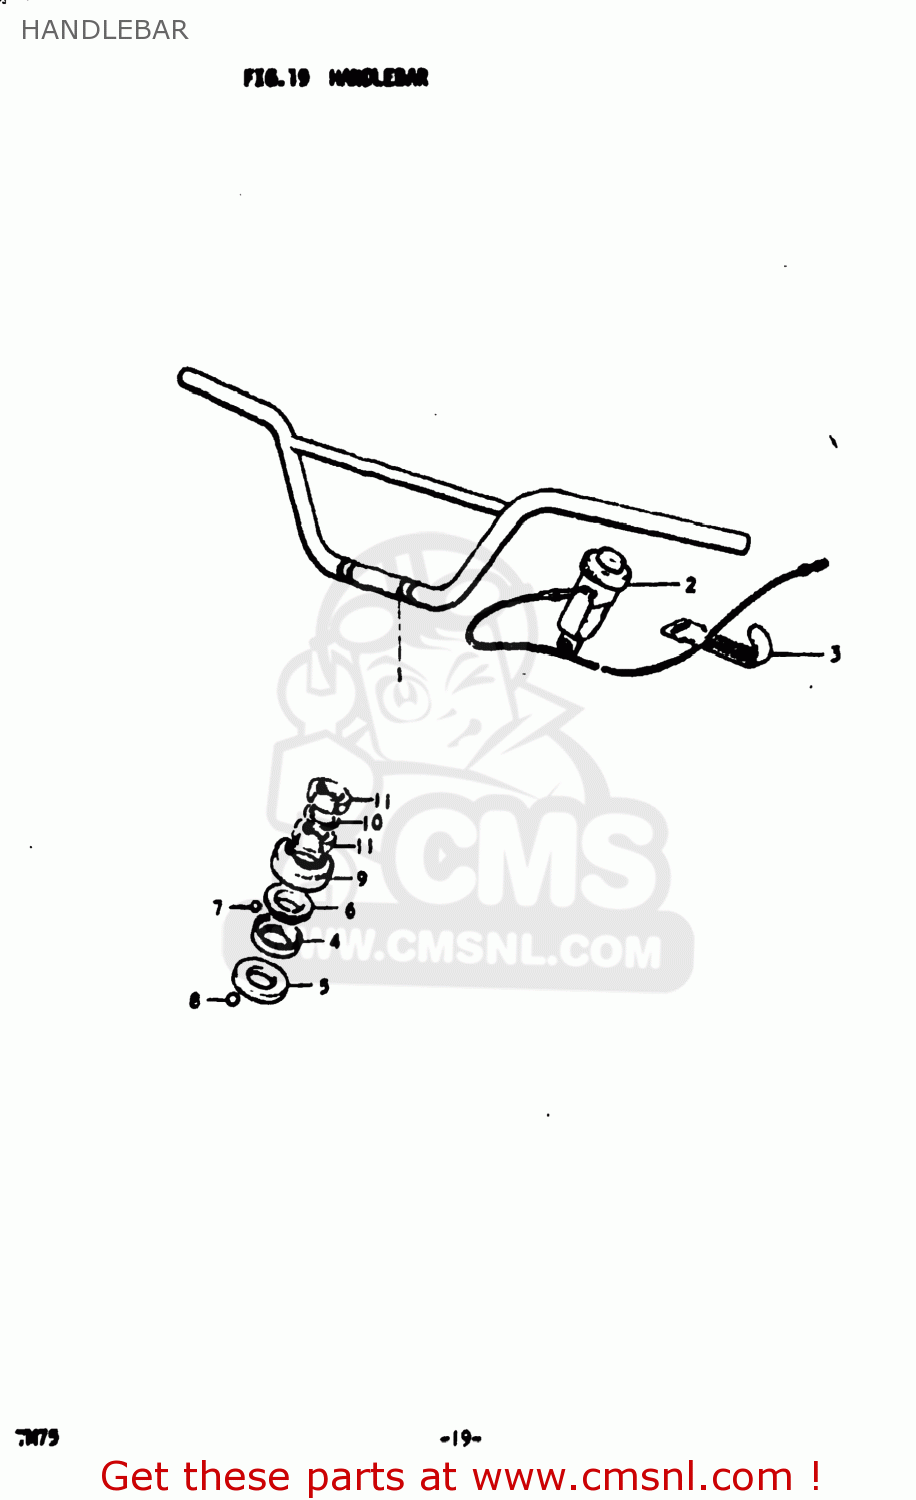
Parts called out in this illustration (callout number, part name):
1	HANDLEBAR
2	SWITCH ASSEMBLY
3	CLAMP
4	RACE,STEERING INNER UPR
5	LACE,STEERING INNER LWR
6	LACE,STEERING OUTER UPR
7	BALL
8	BALL
9	DUST SEAL,STEERING UPR
10	WASHER
11	NUT
